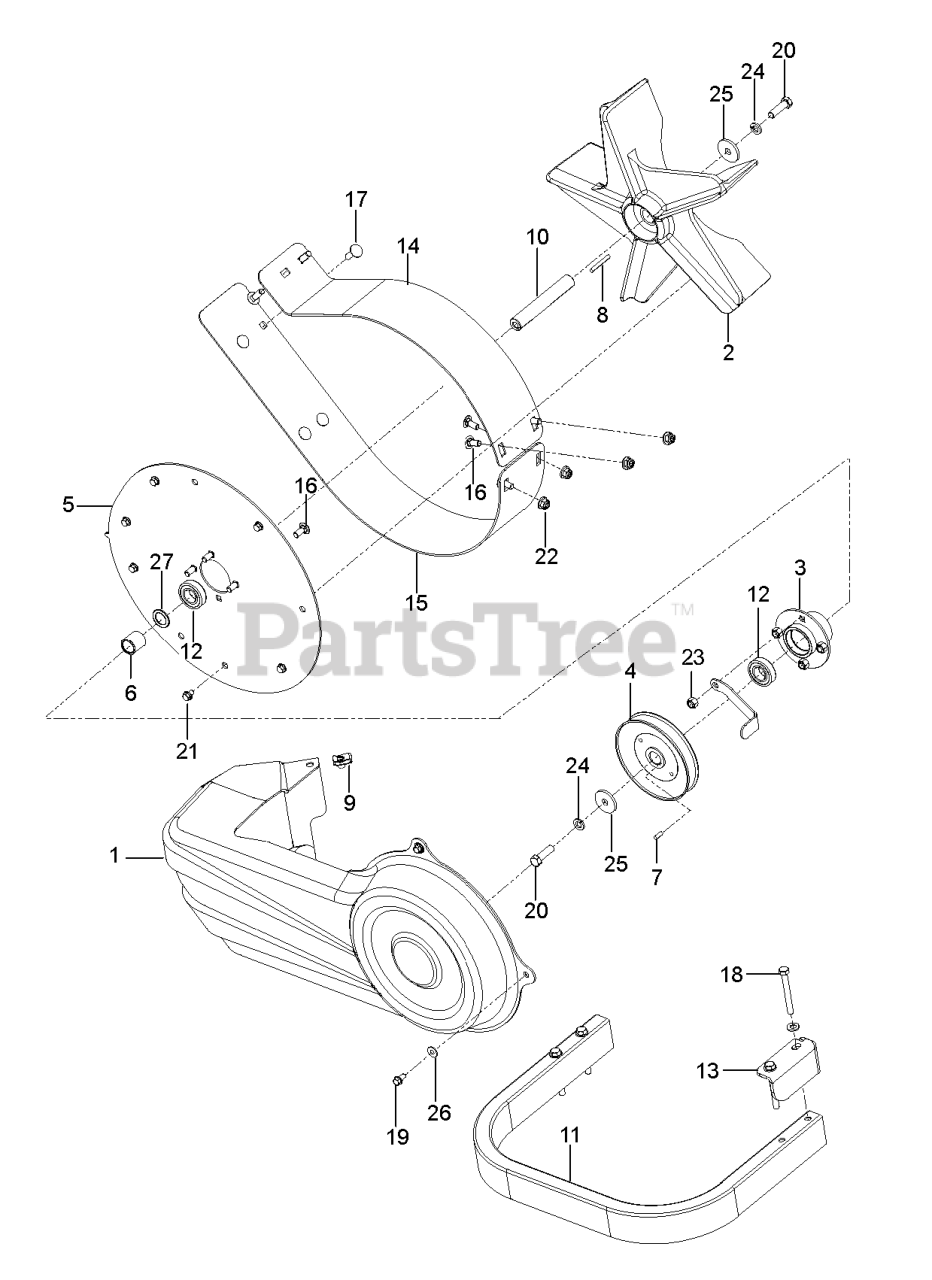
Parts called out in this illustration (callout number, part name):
1	CHASSIS STAMPING
2	DRAWBAR, 12GA
5	BUMPER.RUBBER.HOOD
9	DASH.SLKSCR.SL.PL.C.NA.NHMHUS
10	BOLT D
11	PANEL.DASH.LH.LTX
13	PANEL DASH RH
17	VENT.HOOD.LASER.III
18	BUMPER.HOOD.LARGE.1.75"
25	WASHER
26	NUT
30	FENDER.PNT.LTST.W/S.N/C.422ROS
31	BRACKET FENDER
33	FOOTREST.PNT.LH.BLACK
34	FOOTREST, RH
37	Screw 5/16-18 x 1/2 Hex, Self Tapping 5/16-18 x 1/2
38	BRACKET.ASM.PIVOT.MOWER.REAR
39	BRACKET PIVOT
64	DASH LOWER
142	PLATE REINFORCEMENT
145	ROD.PIVOT.HOOD
206	SHOULDER BOLT 5/16-18TT
207	SCREW, 5/16-18 X 1/2
208	SCREW 3/8-16X1/2
209	SCREW, 3/8-16X3/4
212	INSERT.LENS.REFLECTIVE
258	LENS LH
259	LENS LH
260	COVER.LENS.HUSQ.LASER
272	VENT.HOOD.LASER.
273	VENT.HOOD.LASER.
278	SCREW.#10 X 0.750.BOS
